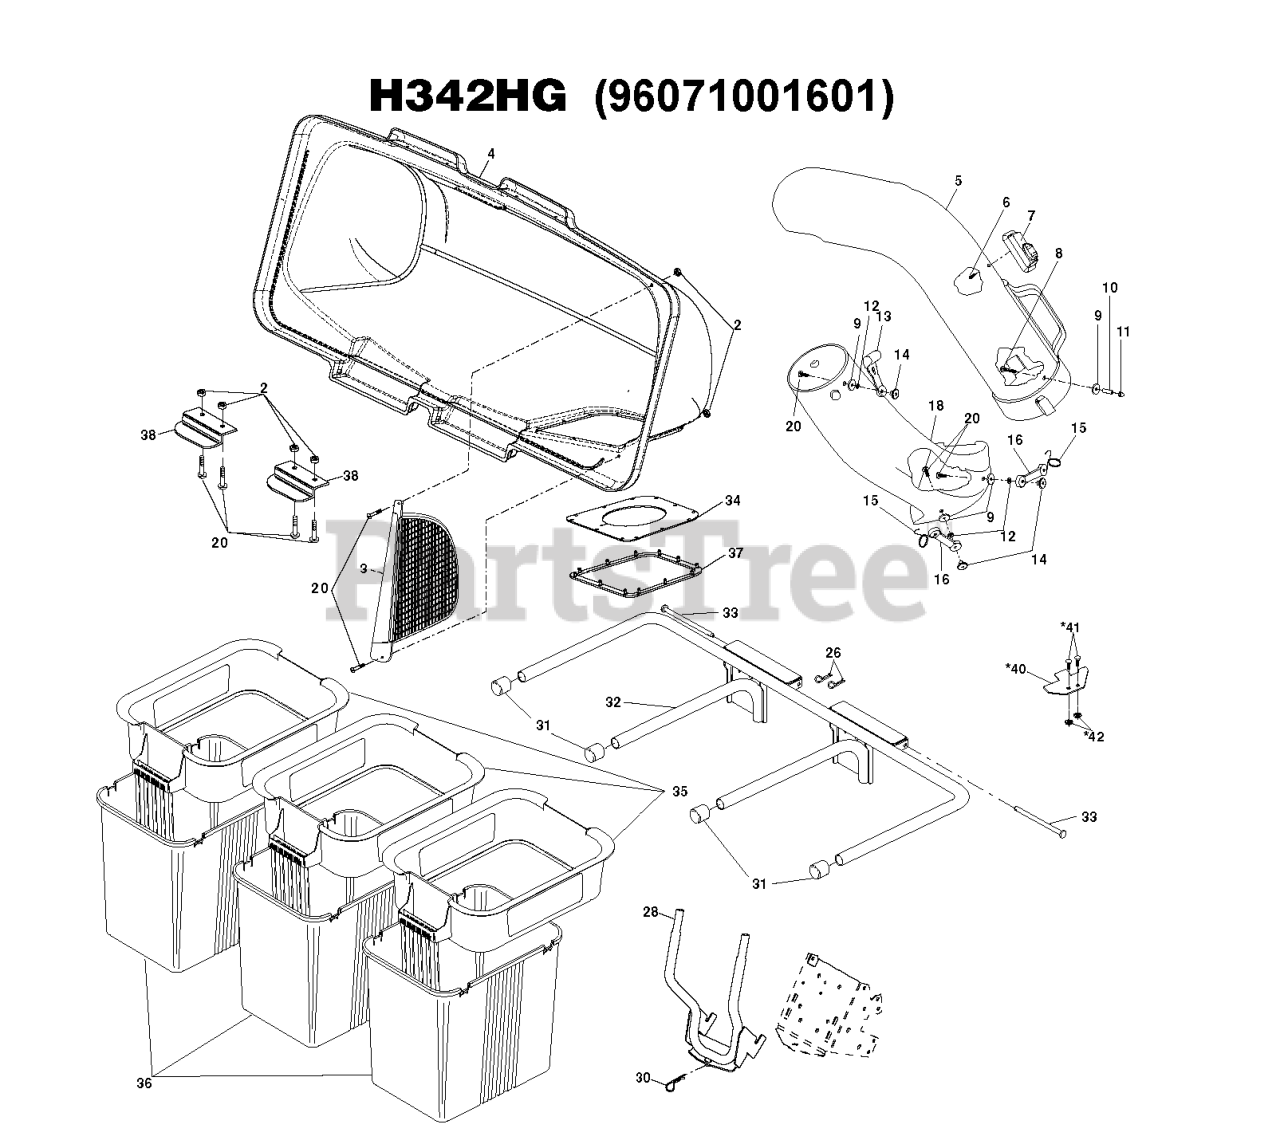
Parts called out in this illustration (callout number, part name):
3	SCREEN.COVER.BAGGER
4	COVER.ASM.3BIN.GENERIC.
5	CHUTE.UPPER.BAGGER.42"
7	INDICATOR ASM BAG
8	SCREW
9	RP STEEL WASHER
11	NUT
12	LOCKWASHER #10
13	LATCH.HOOD.
14	WELDNUT
15	HOOK LATCH
16	RUBBER LATCH
18	LOWER CHUTE FOR 42" BAGGER
20	SCREW
26	RETAINER-SPRNG RB
28	BAGGER.ASM.SUPPORT.GT.TEX.BLAC
30	SPRING.RETAINER.YELLOW.ZINC
31	PLUG, TUBING END
32	BAGGER.ASM.FRAME.3BIN.BLACK
33	BAGGER.HINGE.PIN
34	SEAL.BAGGER.TOP.3-BIN.BLK
35	CONTAINER TOP
36	CONTAINER BOTTOM
37	GASKET.COVER.BAGGER
38	LATCH CER38
40	BRACKET.CHUTE.BAGGER.BLACK
41	BOLT
42	NUT T
